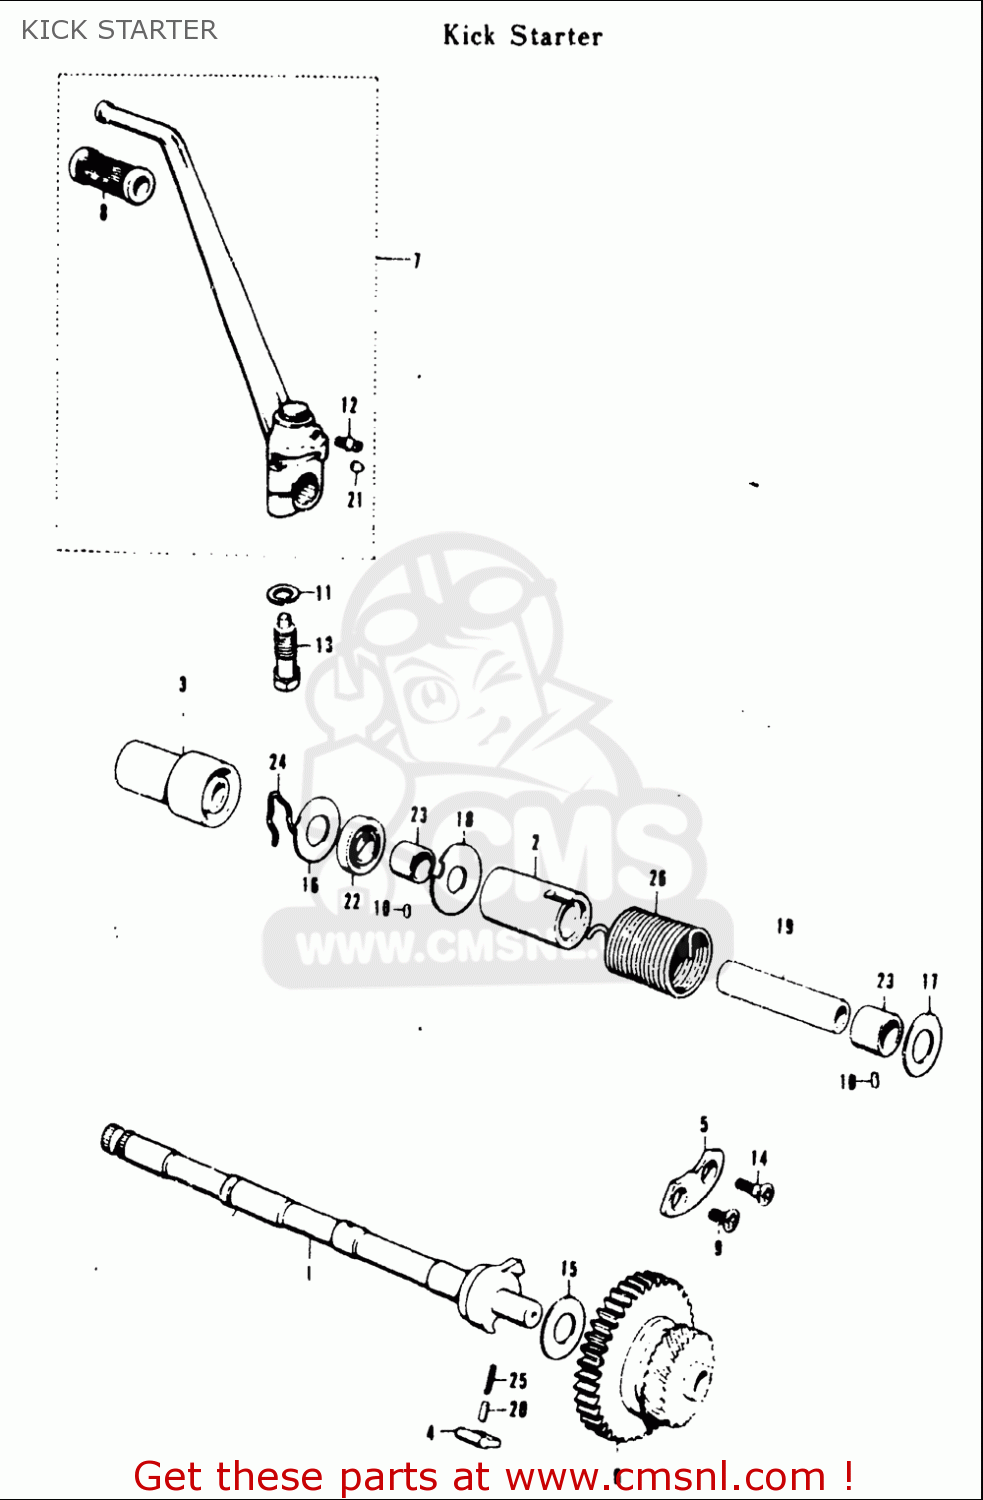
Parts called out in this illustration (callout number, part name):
8	RUBBER,KICK STARTER PEDAL
9	SCREW
10	PIN
11	WASHER,LOCK
12	NIPPLE
13	BOLT(10X37.5)
14	SCREW(6X19)
15	WASHER(13X31.5X1.5)
17	WASHER(16X30X1)
25	SPRING
26	SPRING
